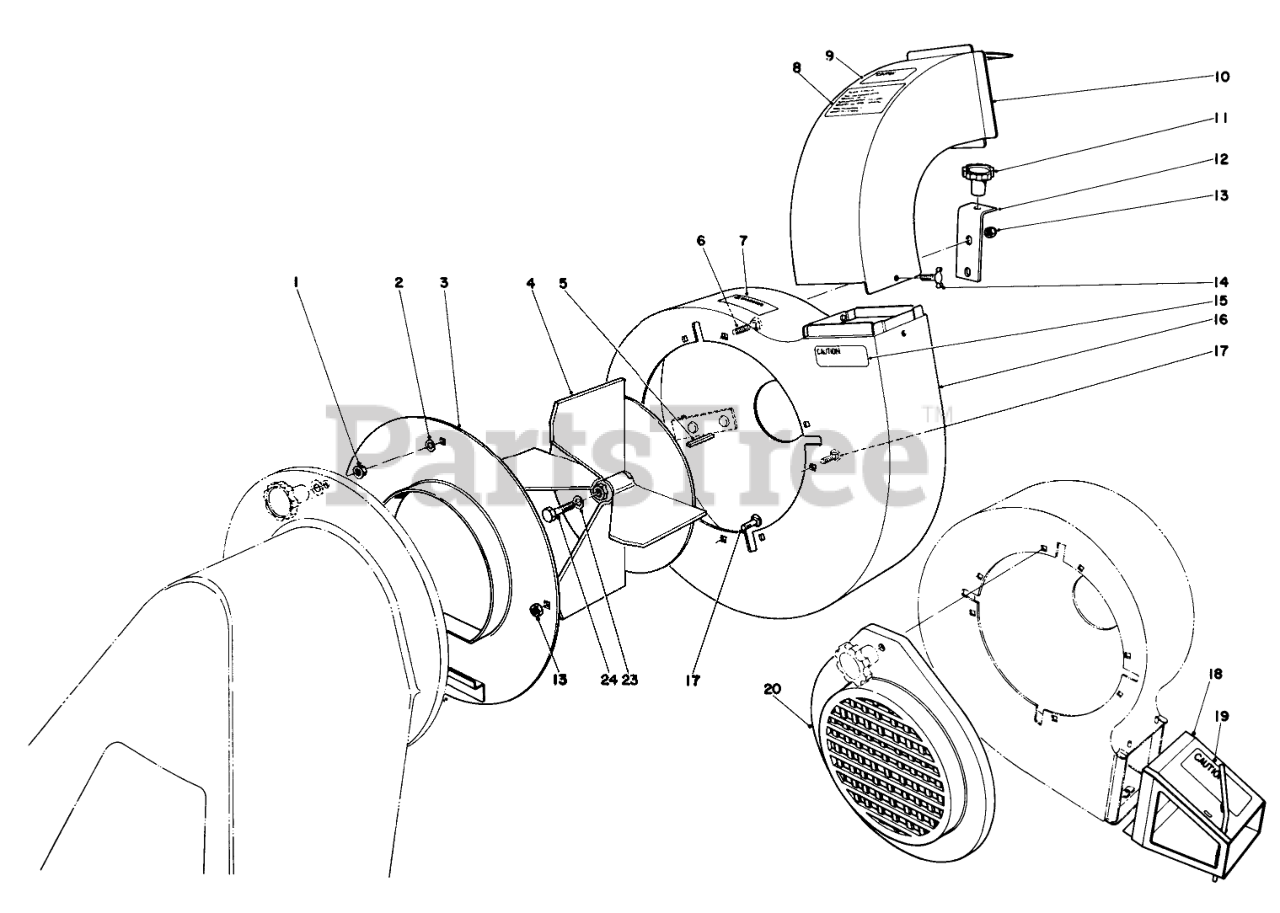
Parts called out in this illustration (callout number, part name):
1	NUT-FLANGE
2	WASHER-FLAT
3	Blower Cover
4	Fan
5	KEY-SQUARE
6	BOLT-CARR
7	ROTATE WARNING DECAL
8	TORO ADVER DECAL
9	DECAL CAUTION BAG
10	Chute-Vacuum
12	Bracket-Housing
13	NUT-LOCK, CONE
14	1/4 - 20 3/4 WING SCR
15	WARNING DECAL
16	Blower Housing
17	SCREW-CARR
18	Blower Exhaust (Incl.Ref. #19)
19	EXHAUST DECAL
20	INTAKE-BLOWER
23	WASHER-LOCK
24	SPEC SCREW
